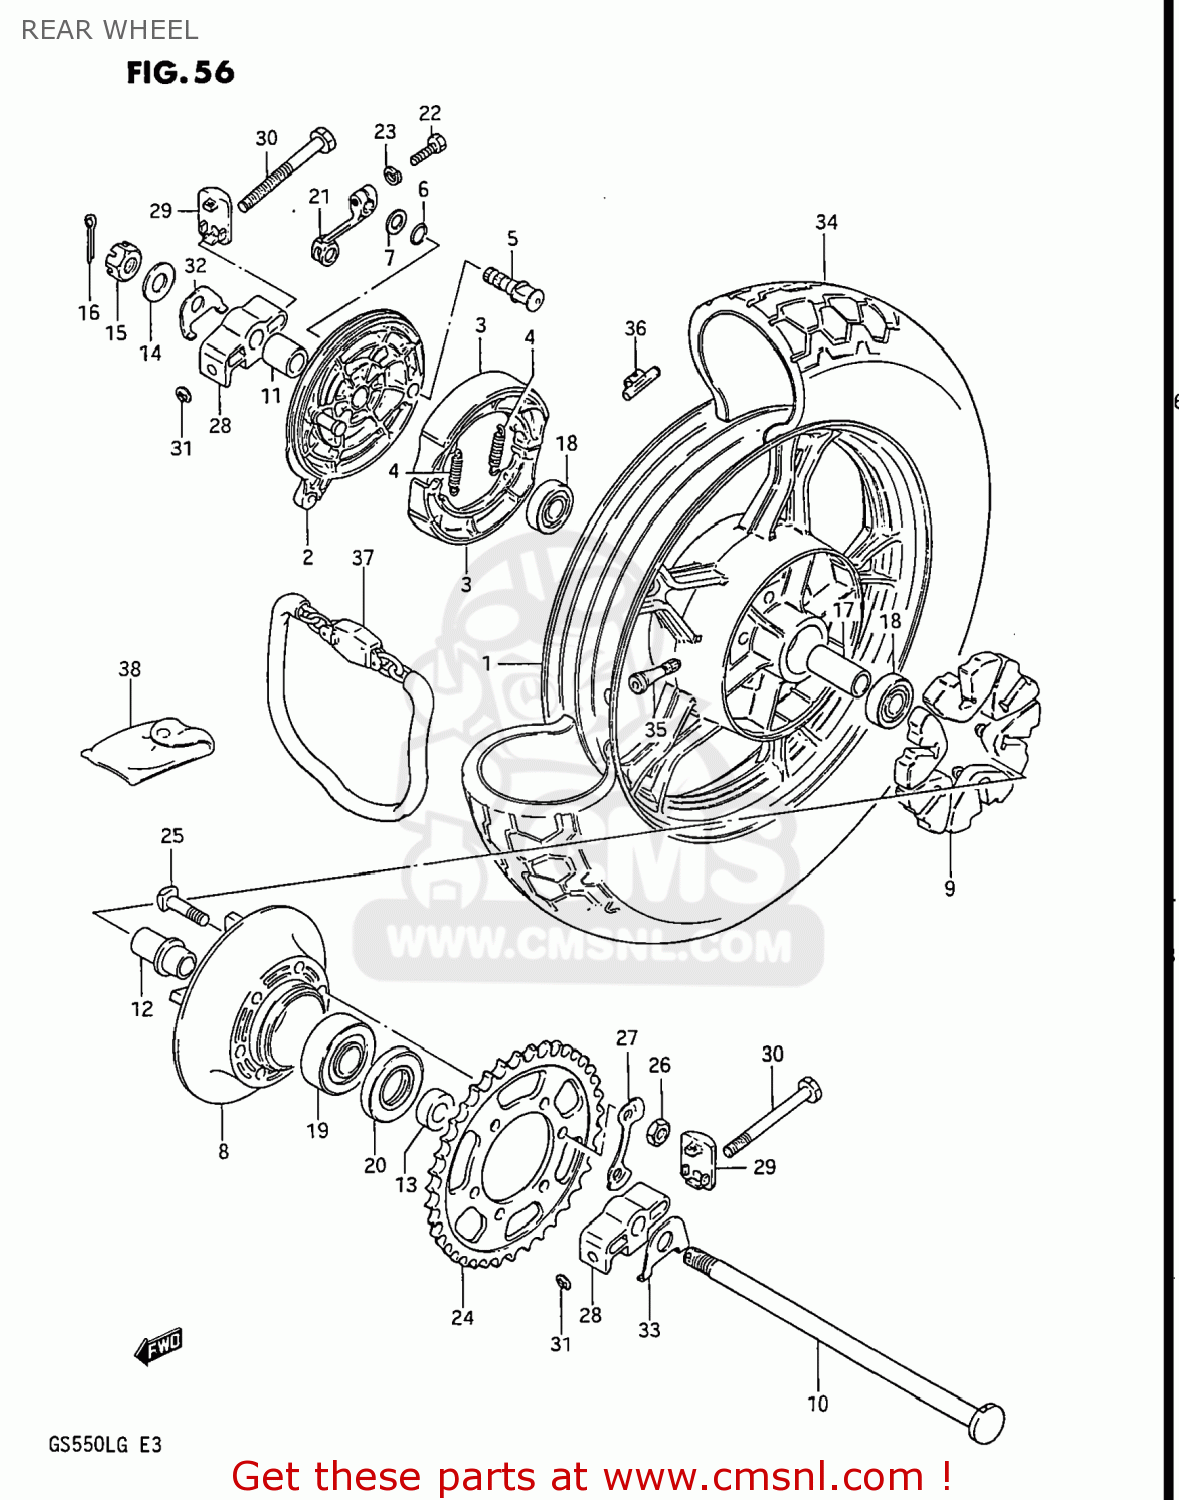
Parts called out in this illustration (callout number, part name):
1	WHEEL,REAR
2	PANEL,REAR HUB
3	SHOE,BRAKE
4	SPRING,BRAKE SHOE
5	CAM,FRONT BRAKE
6	O-RING,BOSS
7	WASHER (15X24X1.6)
8	DRUM,REAR SPROCKET MOUNT
9	ABSORBER,REAR HUB SHOCK
10	AXLE,REAR
11	SPACER (17.5X28X35)
12	RETAINER,RR SPROCKET DRUM
13	SPACER (17X33X12.5)
14	WASHER
15	NUT
16	PIN,COTTER
17	SPACER(17.5X25X70)
18	BEARING
19	BEARING
20	SEAL,OIL(33X62X7)
21	LEVER,REAR BRAKE CAM
22	BOLT
23	WASHER,LOCK
24	SPROCKET,REAR
25	BOLT(10X35.5)
26	NUT
27	WASHER
28	BODY,CHAIN ADJUSTER
29	PLATE,CHAIN ADJUSTER
30	BOLT,CHAIN ADJUSTER
31	E RING
32	WASHER,CHAIN ADJUSTER
33	WASHER,CHAIN ADJUSTER
34	TIRE
35	VALVE,TIRE
36	BALANCER,WHEEL
37	CHAIN LOCK ASSY
38	BAG,CHAIN LOCK
